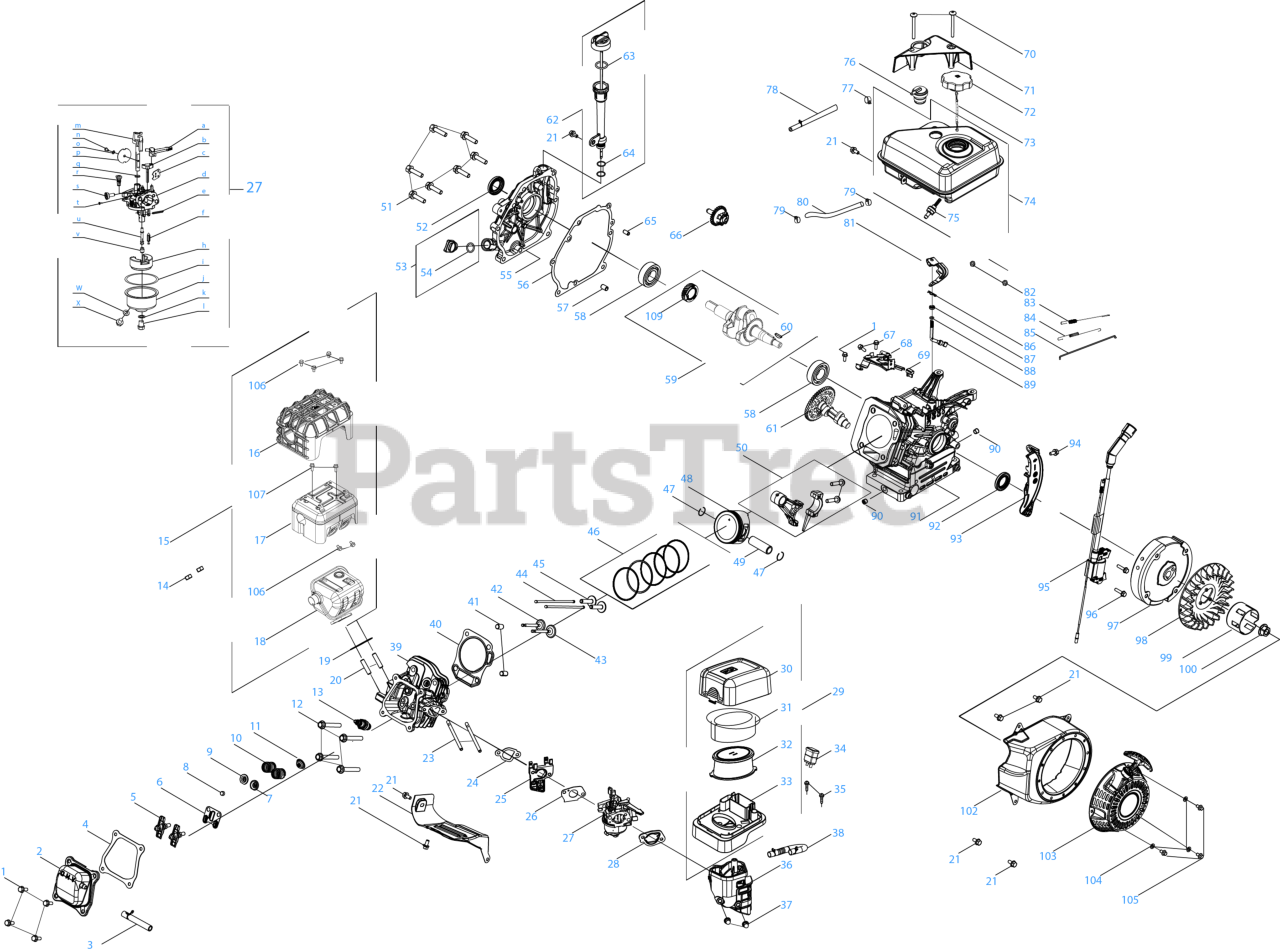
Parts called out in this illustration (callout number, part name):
1	BOLT M6 x 16
2	VALVE COVER
3	BREATHER HOSE
4	VALVE COVER GASKET
5	ROCKER ARM ASSEMBLY
6	ROCKER ARM BASE
7	INTAKE VALVE SPRING RETAINER
8	EXHAUST VALVE ADJUSTER
9	EXHAUST VALVE SPRING RETAINER
10	VALVE SPRING
11	INTAKE VALVE SEAL
12	BOLT-M8-1.25 x 60 GR10.9
13	SPARK PLUG
16	MUFFLER SHIELD
17	INNER MUFFLER SHIELD
18	MUFFLER BODY
19	MUFFLER GASKET
20	STUD M8 x 36
21	BOLT M6-1 x 12 GR8.8
22	AIR SHIELD
23	STUD M6-1 x 110 GR8.8
24	CARBURETOR INSULATOR GASKET
25	CARBURETOR INSULATOR
26	CARBURETOR GASKET
27	CARBURETOR ASSEMBLY
28	CARBURETOR GASKET PLATE
29	AIR FILTER
30	AIR FILTER COVER
31	AIR FILTER
32	AIR CLEANER WITH PRE-FILTER
33	SILENCER PLATE
34	CARBON CANISTER
35	SCREW M4x20
36	AIR CLEANER HOUSING
38	PRIMER HOSE
39	CYLINDER HEAD
40	CYLINDER HEAD GASKET
42	EXHAUST VALVE
43	INTAKE VALVE
44	PUSH ROD
46	PISTON RING 4PC SET
47	PISTON PIN SNAP RING
49	PISTON PIN
50	CONNECTING ROD ASSEMBLY
51	BOLT M8-1.25 x 32 GR5.8
52	OIL SEAL 25 x 41.25 x 6
54	O-RING 15.8 x 2.5
55	CRANKCASE COVER
56	CRANKCASE COVER GASKET
57	DOWEL PIN
59	CRANKSHAFT
60	FLYWHEEL KEY
62	DIPSTICK ASSEMBLY
63	DIPSTICK O-RING
64	OIL FILL TUBE O-RING
65	DOWEL PIN
66	GOVERNOR GEAR/SHAFT ASSEMBLY
67	BOLT M6-1 x 12 GR8.8
68	GOVENOR GEAR BRACKET
69	THROTTLE KNOB
70	BOLT M6-1 x 67
71	ENGINE/DIPSTICK COVER
72	FUEL CAP BLACK
75	FUEL INLET NIPPLE
76	ROLLOVER VALVE
77	FUEL HOSE CLAMP
78	HOSE ASSEMBLY
79	HOSE CLAMP
80	FUEL HOSE (6.3x12.5x123MM)
81	GOVERNOR LEVER
83	GOVERNOR SPRING
84	THROTTLE RETURN SPRING
85	GOVERNOR ROD
86	COTTER PIN
87	GOVERNOR SEAL
89	GOVERNOR SHAFT
90	OIL DRAIN PLUG
92	OIL SEAL-25 x 41.25 x 6
93	LOWER SHIELD
94	SCREW M6-1 x 20 CL5.8
95	IGNITION COIL
96	BOLT M6-1 x 25 GR8.8
98	COOLING FAN
99	STARTER CUP
100	FLYWHEEL NUT
102	BLOWER HOUSING
103	RECOIL STARTER
104	RECOIL FLAT WASHER
105	BOLT M6 x 10
106	BOLT M5-.8 x 8 CL10.9
107	BOLT M5-.8 x 12 CL10.9
109	DRIVE TIMING GEAR
